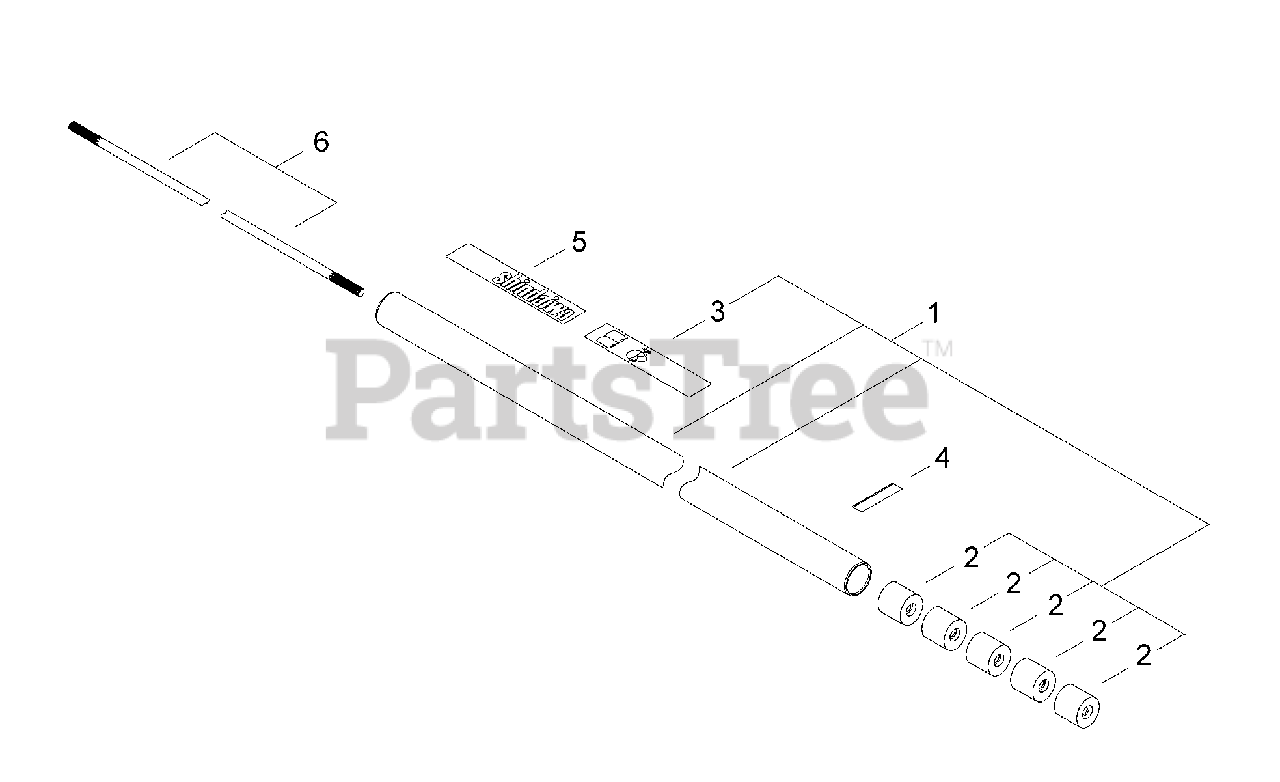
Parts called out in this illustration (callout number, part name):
1	MAIN PIPE ASSY
2	BUSHING
3	LABEL, CAUTION (NON-BLADE CAPABLE)
4	LABEL, HANDLE
5	LABEL, SHINDAIWA PROFESSIONAL
6	MAINSHAFT
